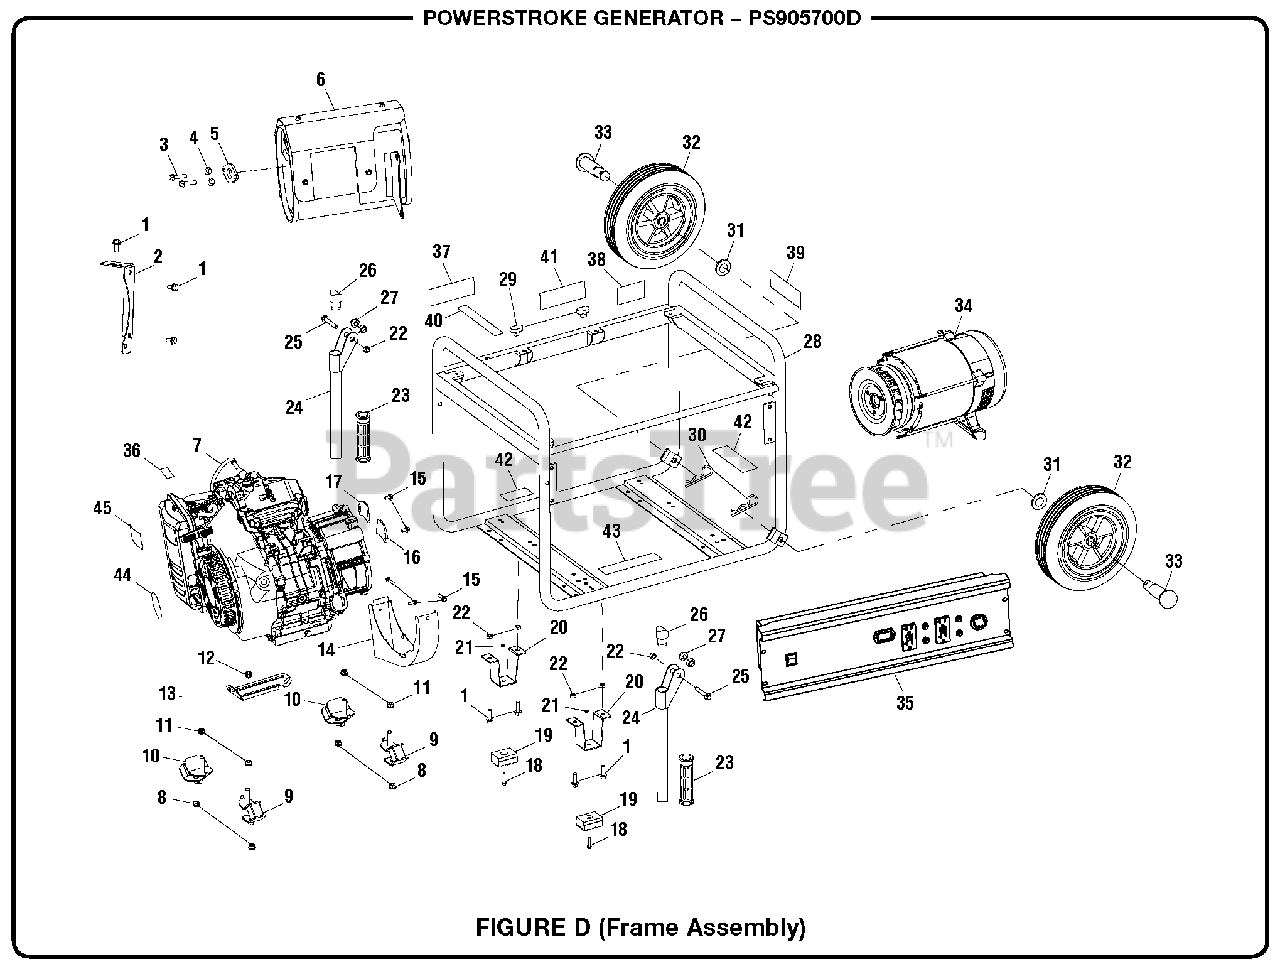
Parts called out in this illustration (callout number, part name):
2	Muffler Bracket
4	Spring Washer
5	Gasket (Muffler)
7	Engine
11	Nut
12	Nut
13	Air Filter Bracket
14	Guard Cover (Crankcase)
16	Dustproof Sheet A
17	Dustproof Sheet B
18	Bolt
19	Vibration Isolator
23	Rubber Handle
24	Handle Assembly
27	Handle Bushing
28	Frame Assembly
29	Vibration Isolation Pad
31	Flat Washer
34	Generator Head
35	Control Panel
36	Choke Label
37	Inquiries Label
38	Combustion Label
39	Fire Distance Label
40	Fire Danger Label
41	Ground Warning Label
42	Hot Surface Label
43	Lubricant Label
44	Recoil Label
45	Starting Label
